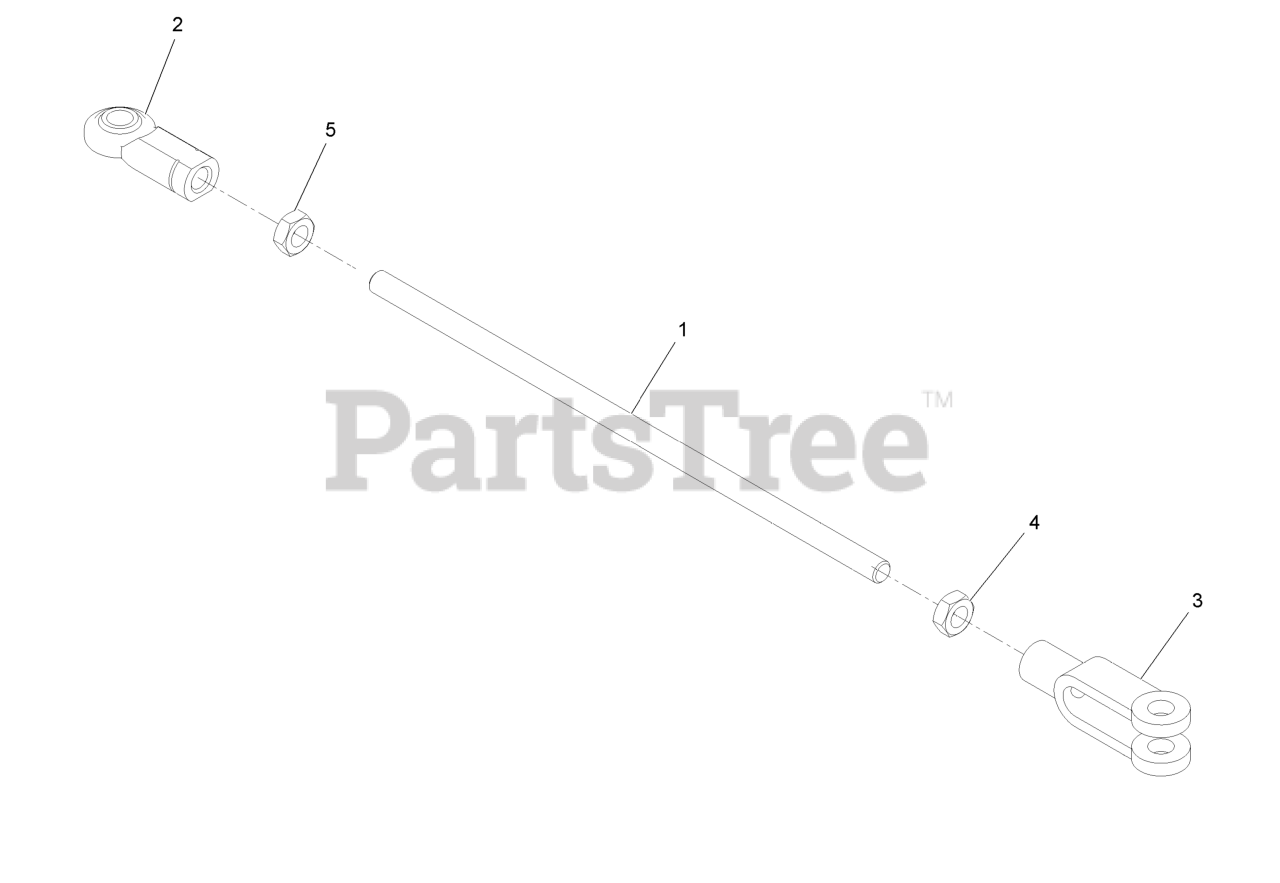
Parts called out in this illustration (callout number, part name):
1	ROD-BRAKE LINKAGE
2	JOINT-BALL END, LH
3	YOKE-LINKAGE, BRAKE
4	NUT-HJ
5	NUT-HEX JAM, LH
